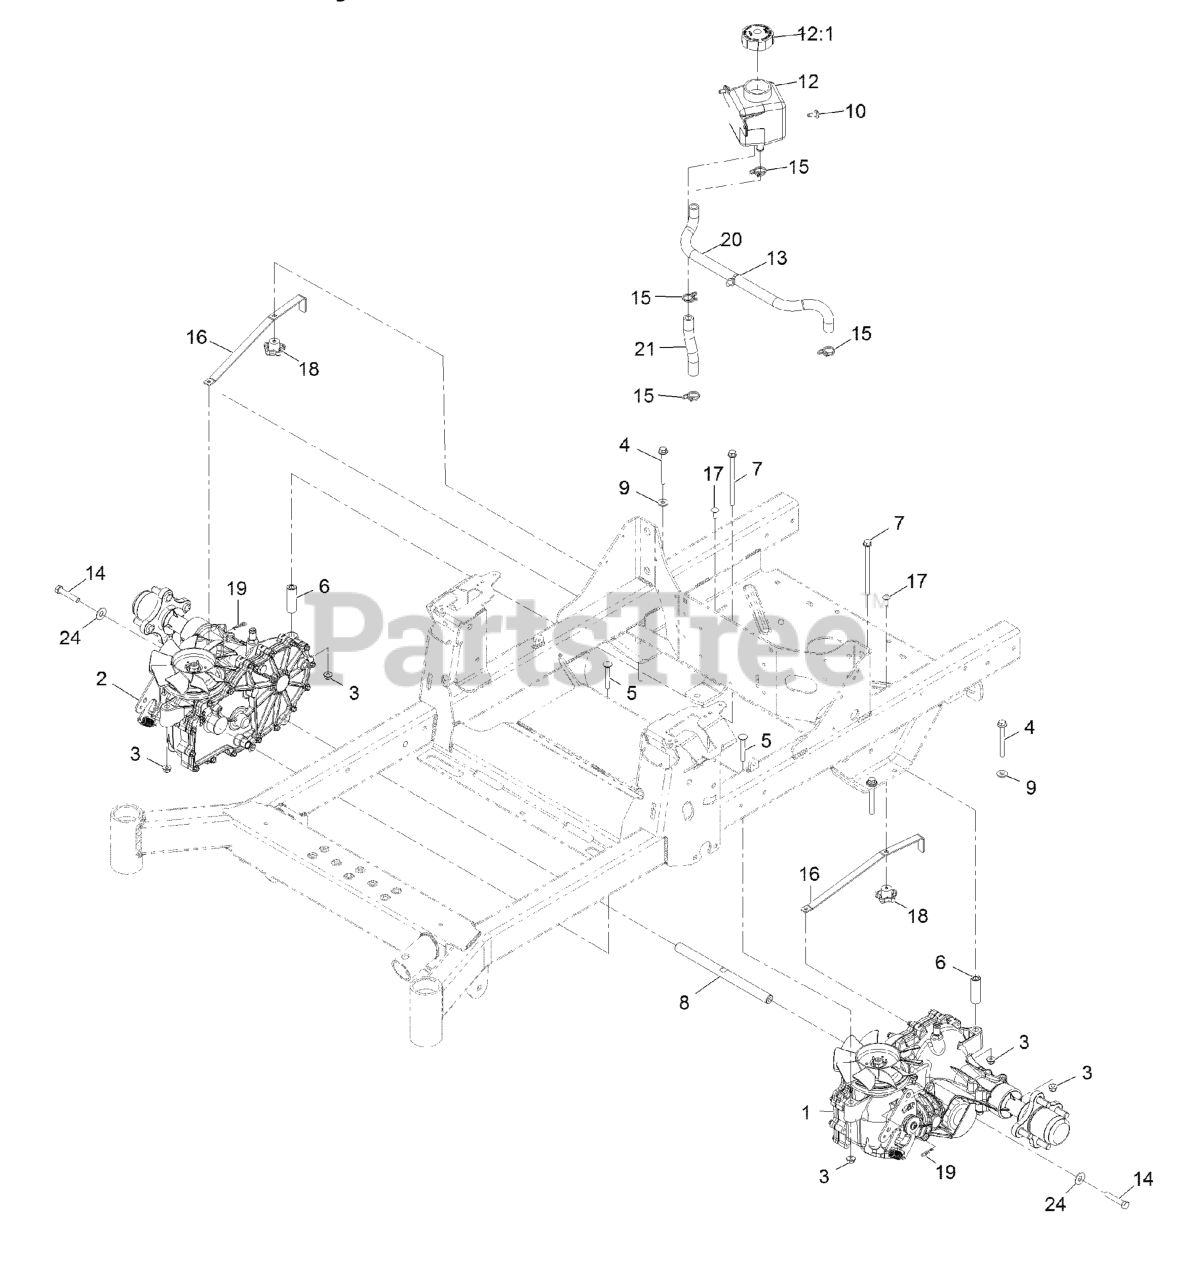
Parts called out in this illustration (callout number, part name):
1	TRANSAXLE ASM LH
2	TRANSAXLE ASM RH
3	NUT-HF, NI
4	SCREW-HHF
5	BOLT-CARR
6	SPACER-HYDRO
7	SCREW HHF
8	SHAFT-SPACER
9	WASHER-SPRING
10	SCREW-TORX
12	TANK-HYD
12:1	CAP-RESERVOIR, HYD
13	CLIP-TIE
14	SCREW-HH W/LOCTITE
15	CLAMP-HOSE
16	ARM-BYPASS, HYDRO
17	BOLT-CARR
18	KNOB-HANDLE
19	PIN-COTTER
20	HOSE-HYDRAULIC
21	HOSE-HYDRAULIC
24	WASHER-FLAT
